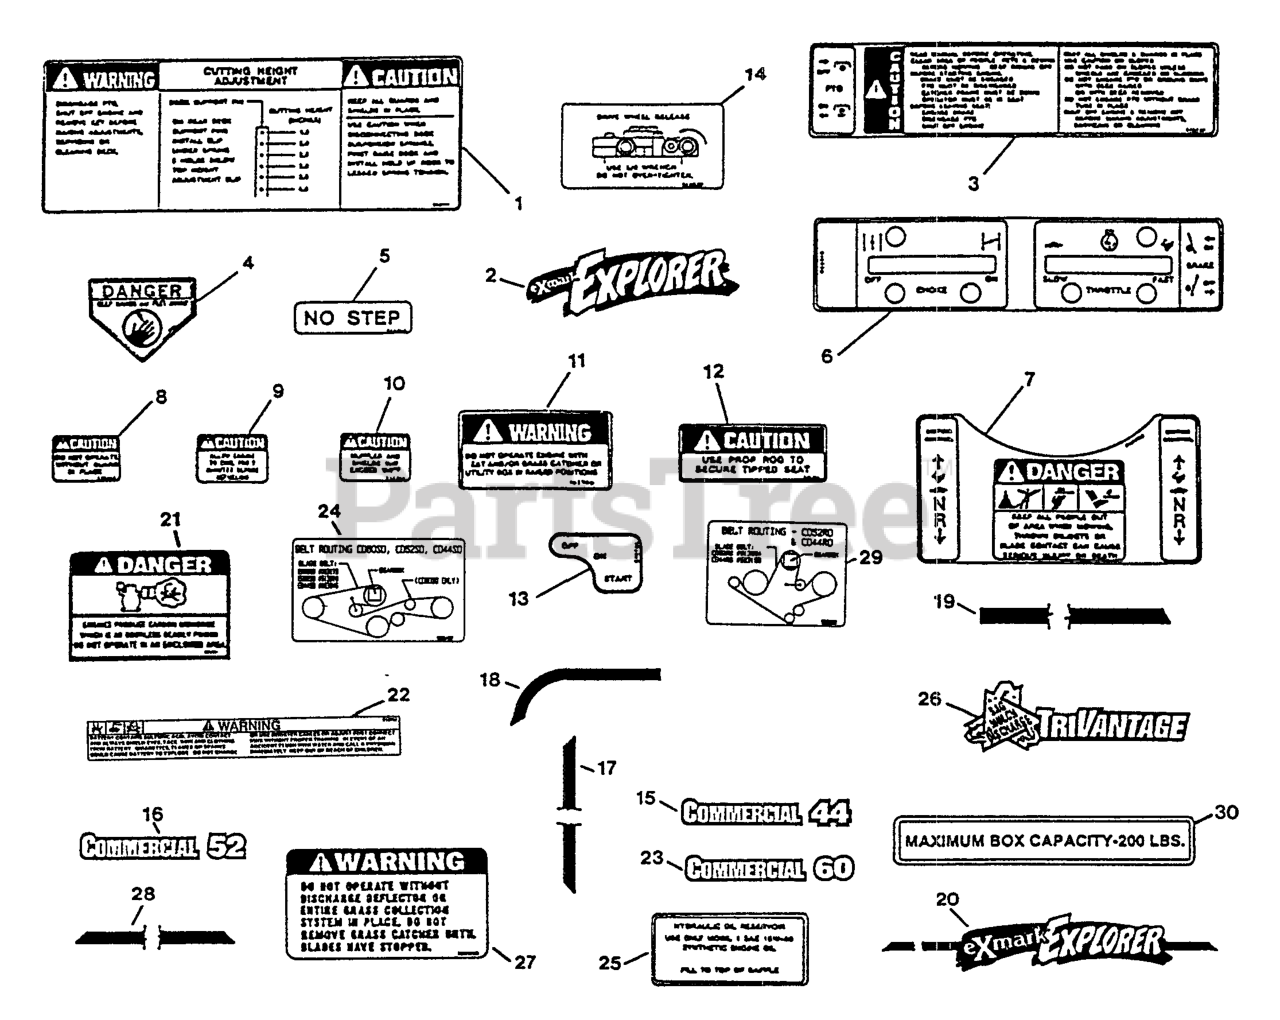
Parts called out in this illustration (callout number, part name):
2	DECAL,EXMARK EXPLORE
3	DECAL,FENDER RH
4	DECAL-DANGER
5	DECAL,NO STEP
7	DECAL,CONSOLE
8	DECAL-GUARD
15	DECAL,COMMERCIAL 44
16	DECAL,COMMERCIAL 52
17	DECAL,CATCHER FRONT
18	DECAL,LH CATCHER STR
22	DECAL-BATTERY
23	DECAL,COMMERCIAL 60
25	DECAL,HYD TANK
27	DECAL-WARNING, DISCHARGE
29	DECAL,BELT RTNG CD52RD
